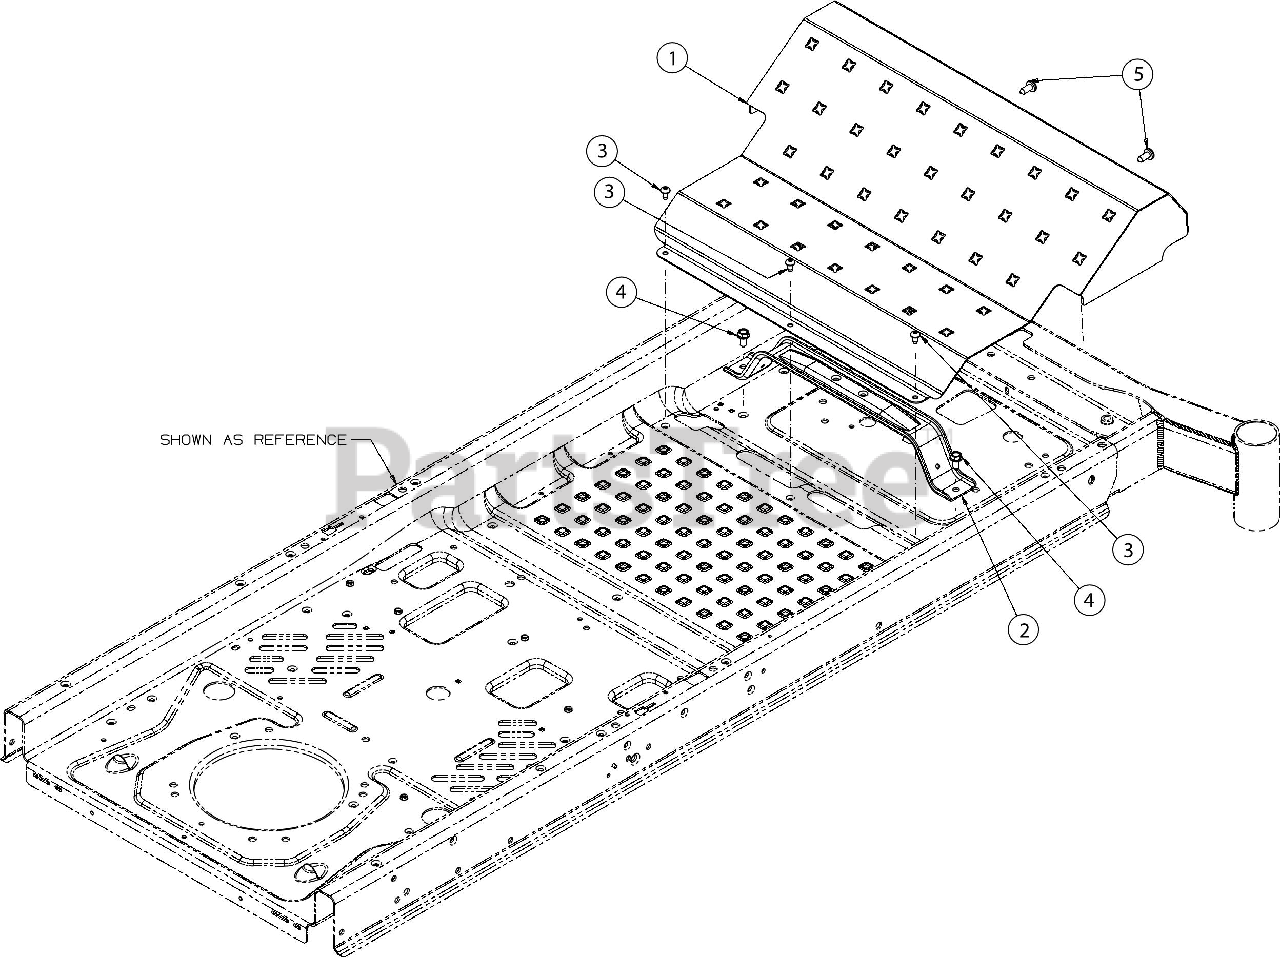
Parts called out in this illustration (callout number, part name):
2	STEERING SUPPORT BRACKET
3	SCREW 1/4-20 X .500
4	SCREW 5/16-18 X .750
5	SCREW 5/16-18 X .750
